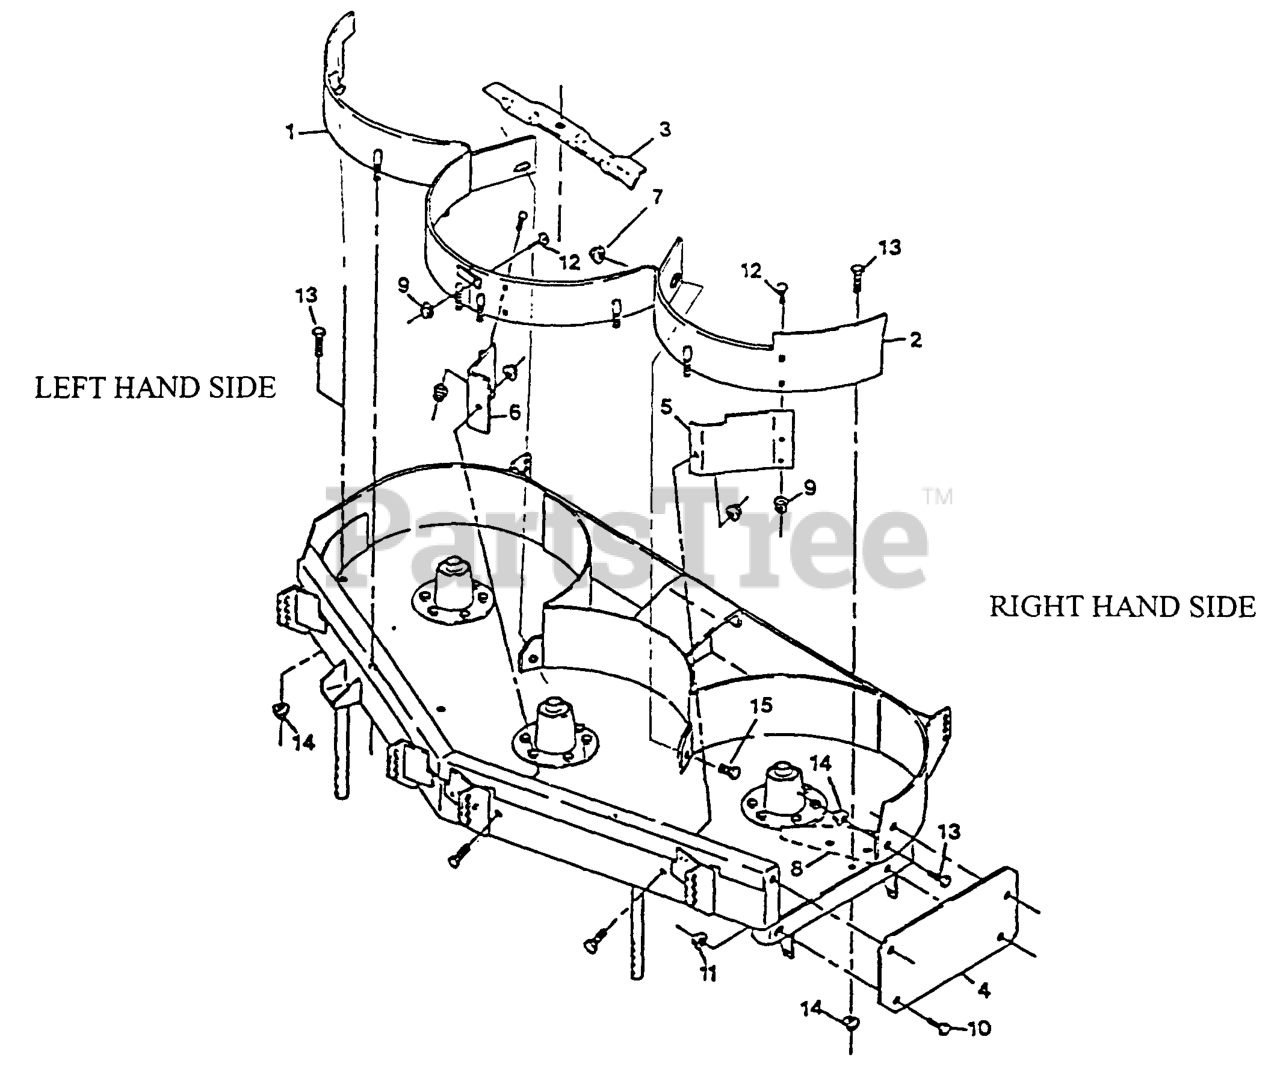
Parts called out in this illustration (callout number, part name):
1	WLD,BAFFLELH52 FMD
4	PLATE-COVER, 48"/52"
8	WLD,BAFFLE DISCHARGE
12	BOLT-CARR
